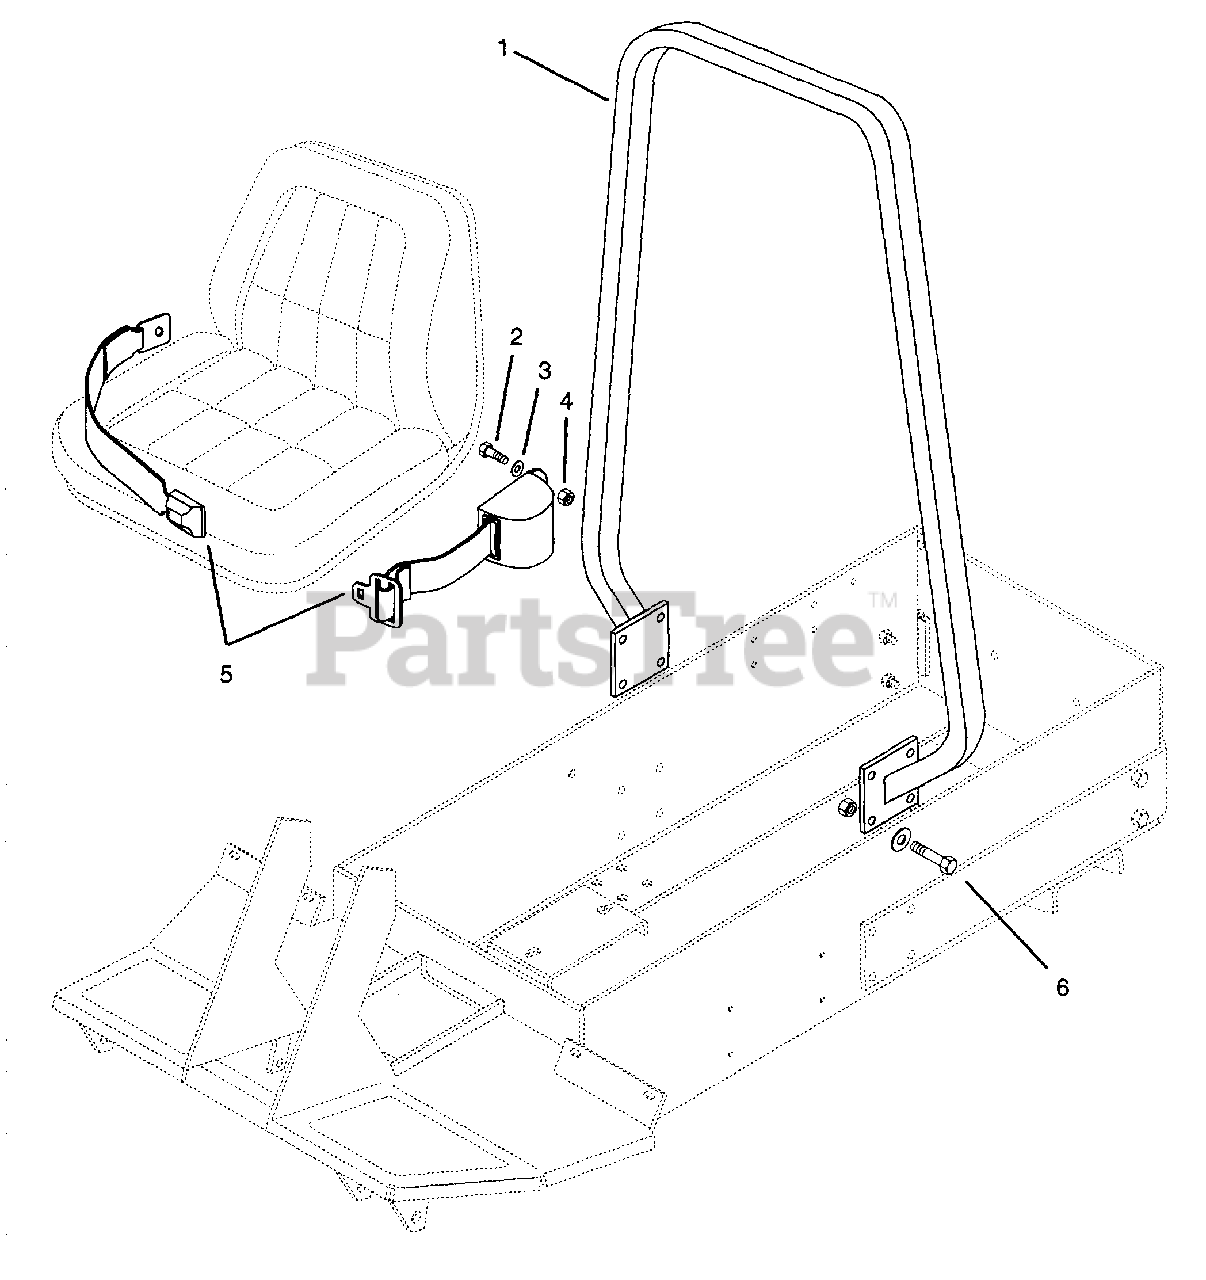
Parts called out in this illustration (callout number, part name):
1	Weldment, Rollover Bar
2	Bolt-Hex .44-14 x 1.0 Grade 5
3	Washer-Flat-Steel .531 x 1.06 x .095
4	Nut-Locking-Center .44-14
5	Assembly, Seat Belt
6	Bolt-Hex .50-13 x 1.75 Grade 8
